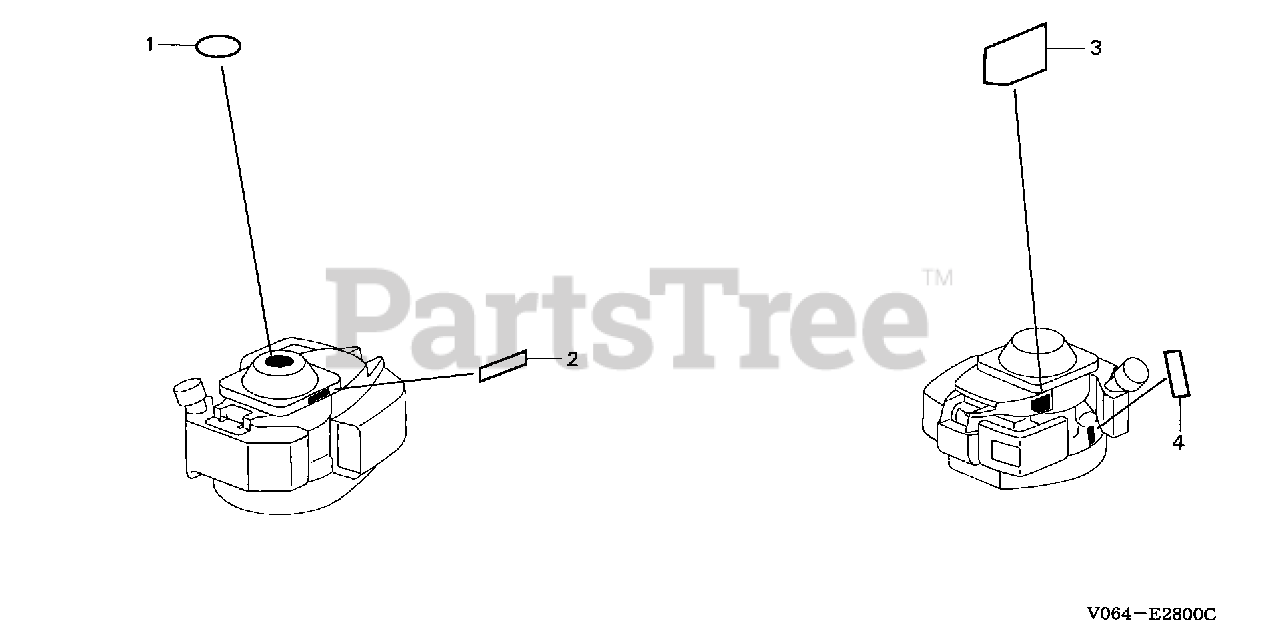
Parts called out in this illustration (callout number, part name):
1	EMBLEM (GX31)
2	MARK, EX. CAUTION
3	MARK, OIL CAUTION (ENGLISH)
4	MARK, TYPE (FK22)
